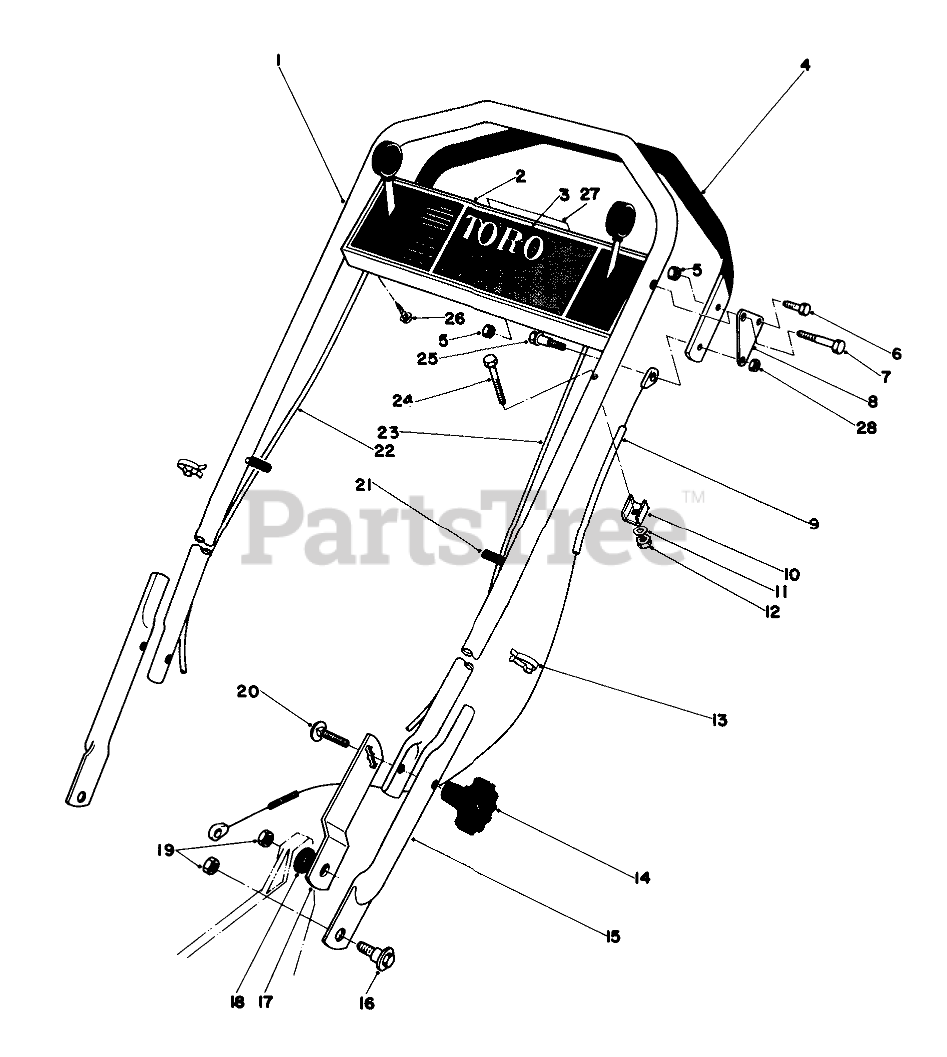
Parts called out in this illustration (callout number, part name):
1	Upper Handle
2	Control Plate
3	Decal-Control Panel
4	DEMAND HANDLE ASM
5	NUT-LOCK, CONE
6	SCREW-HH
7	BOLT-SHOULDER
8	Bracket Demand
9	DEMAND HAND CABLE
10	CLAMP-CABLE
11	WASHER-FLAT
12	NUT-LOCK, NI
13	BOWDEN CLIP
15	LOWER HANDLE
16	SCREW-SHOULDER
17	Handle Latch L.H.
18	SPACER
19	Nut
20	SCREW-CARR
21	CAP-VINYL
22	GROUND SPEED CONTROL
23	Throttle Control
24	SCREW-HH
25	Shoulder Bolt
26	SCREW-HWHTF
27	Decal-Select-a-Pace
28	NUT-HEX, SIDE DEFORM
